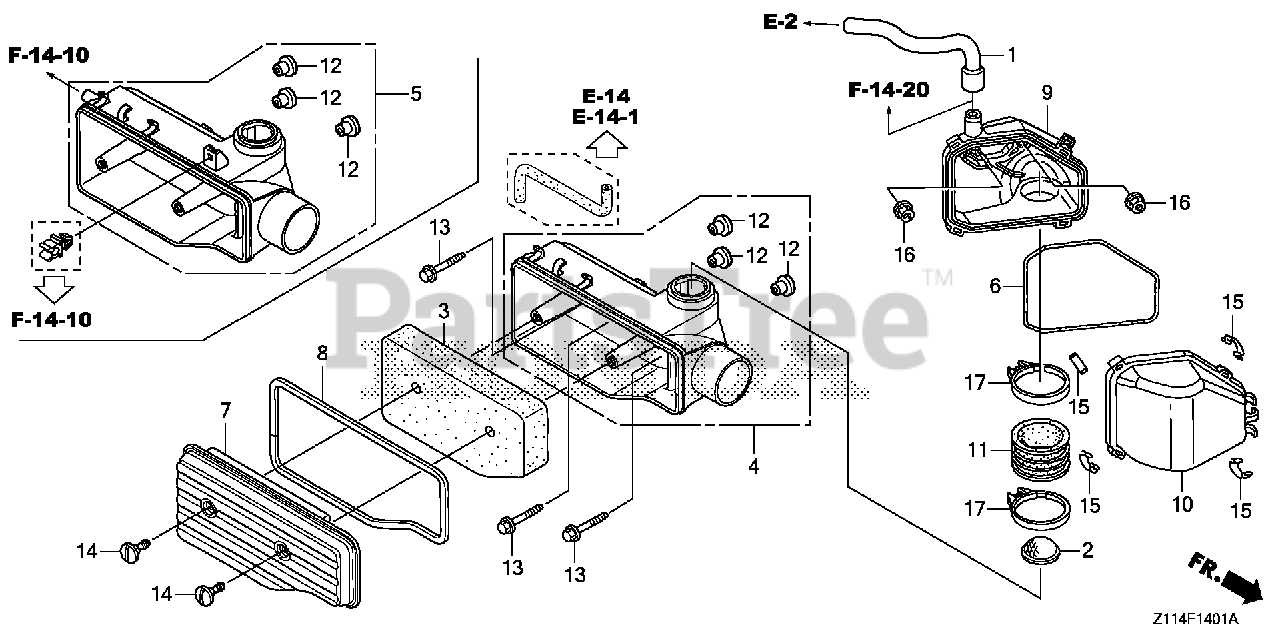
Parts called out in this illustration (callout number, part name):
1	TUBE, BREATHER
2	TRAP, FLAME
3	ELEMENT, AIR CLEANER
5	HOUSING, AIR CLEANER
6	SEAL, AIR CLEANER CHAMBER
7	COVER, AIR CLEANER
8	SEAL, AIR CLEANER COVER
9	HOUSING, AIR CLEANER CHAMBER
10	COVER, AIR CLEANER CHAMBER
11	TUBE, AIR CLEANER CONNECTING
12	COLLAR, FAN COVER
13	BOLT, FLANGE (6X23) (CT200)
14	BOLT, AIR CLEANER COVER (- SCREW)
15	CLAMP, CASE
16	NUT, FLANGE (6MM)
17	BAND, AIR CLEANER CONNECTING TUBE (54)
